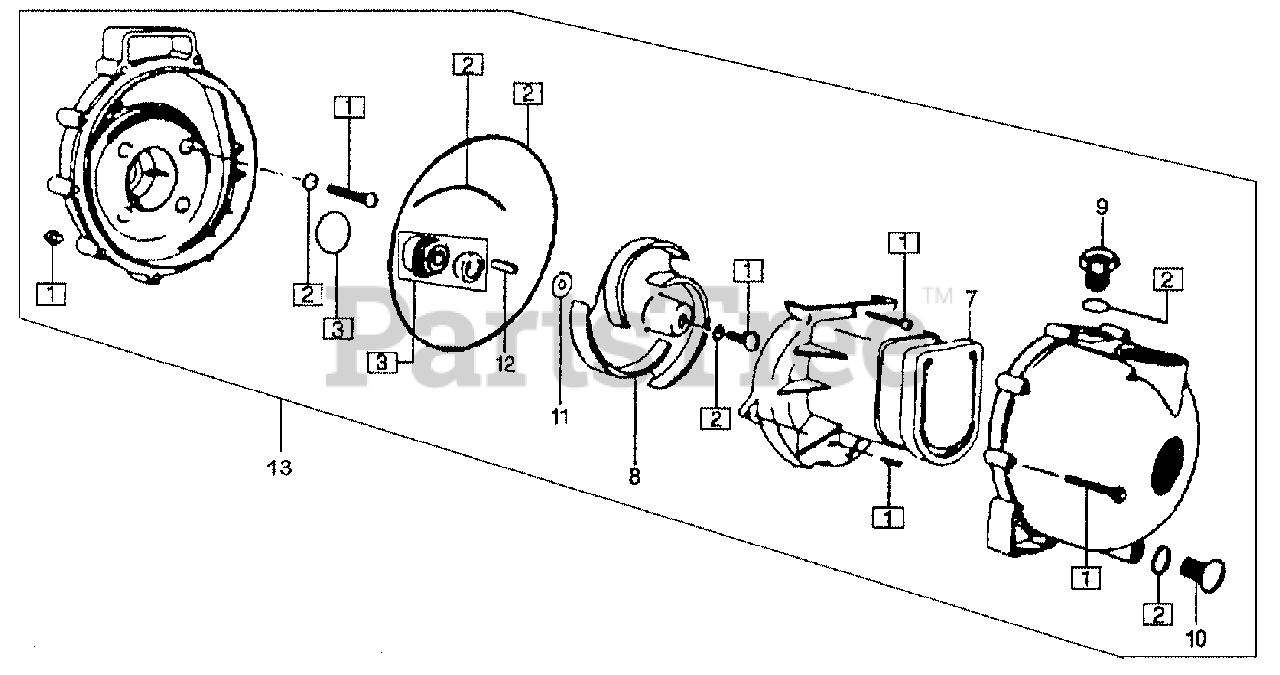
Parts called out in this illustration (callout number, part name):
1	HARDWARE SET
2	O-RING SET
3	SEAL SET, MECHANICAL
7	VALVE, CHECK
9	CAP, FILLER
10	PLUG, DRAIN
11	SHIM A (1.5MM/.006)
11	SHIM B (3.8MM/.015)
11	SHIM C (7.6MM/.030)
13	PUMP ASSY.
